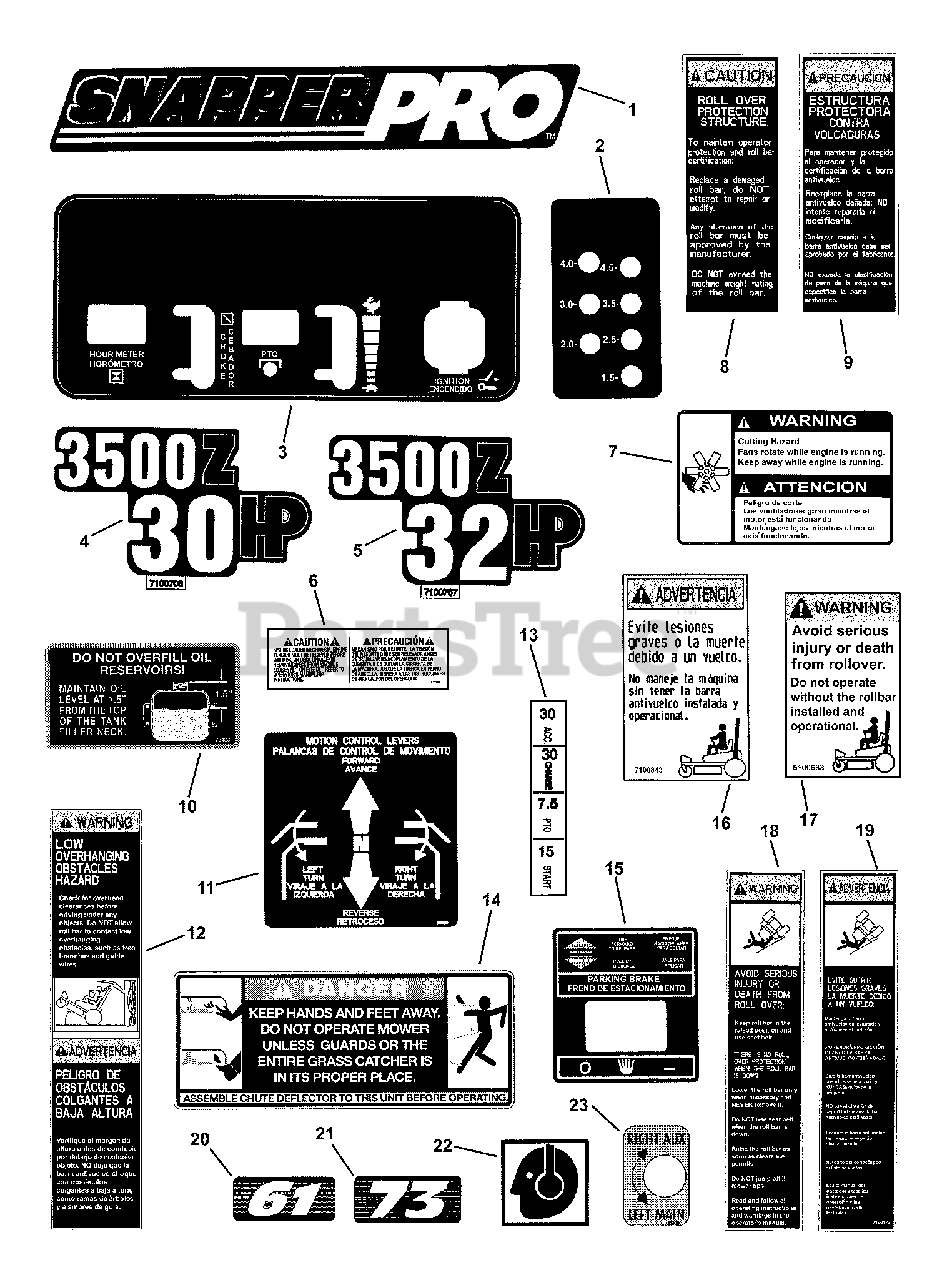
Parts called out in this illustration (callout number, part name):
1	DECAL, Snapper Pro
2	DECAL, Detent Channel
3	DECAL, Control Panel
4	DECAL, 3500 Z, 30 HP
5	DECAL, 3500 Z, 32 HP
6	DECAL, Caution, Spring Tension
7	DECAL, Caution Fan
8	DECAL, Caution ROPS
9	DECAL, Caution ROPS (Spanish)
10	DECAL, Oil Reservoir Overfill Warning
11	DECAL, Motion Control Levers
12	DECAL, ROPS Overhang
13	DECAL, Fuse
14	DECAL, Danger, Guard/Catcher
15	DECAL, Parking Brake Lever & Lights
16	DECAL, Warning (SP)
17	DECAL, Warning, Rollbar
18	DECAL, Warning ROPS
19	DECAL, Warning ROPS (Spanish)
20	DECAL, 61" Deck, (silver)
21	DECAL, 73" Deck
22	DECAL, Ear Protection
23	DECAL, Tank Selector, MMZ
